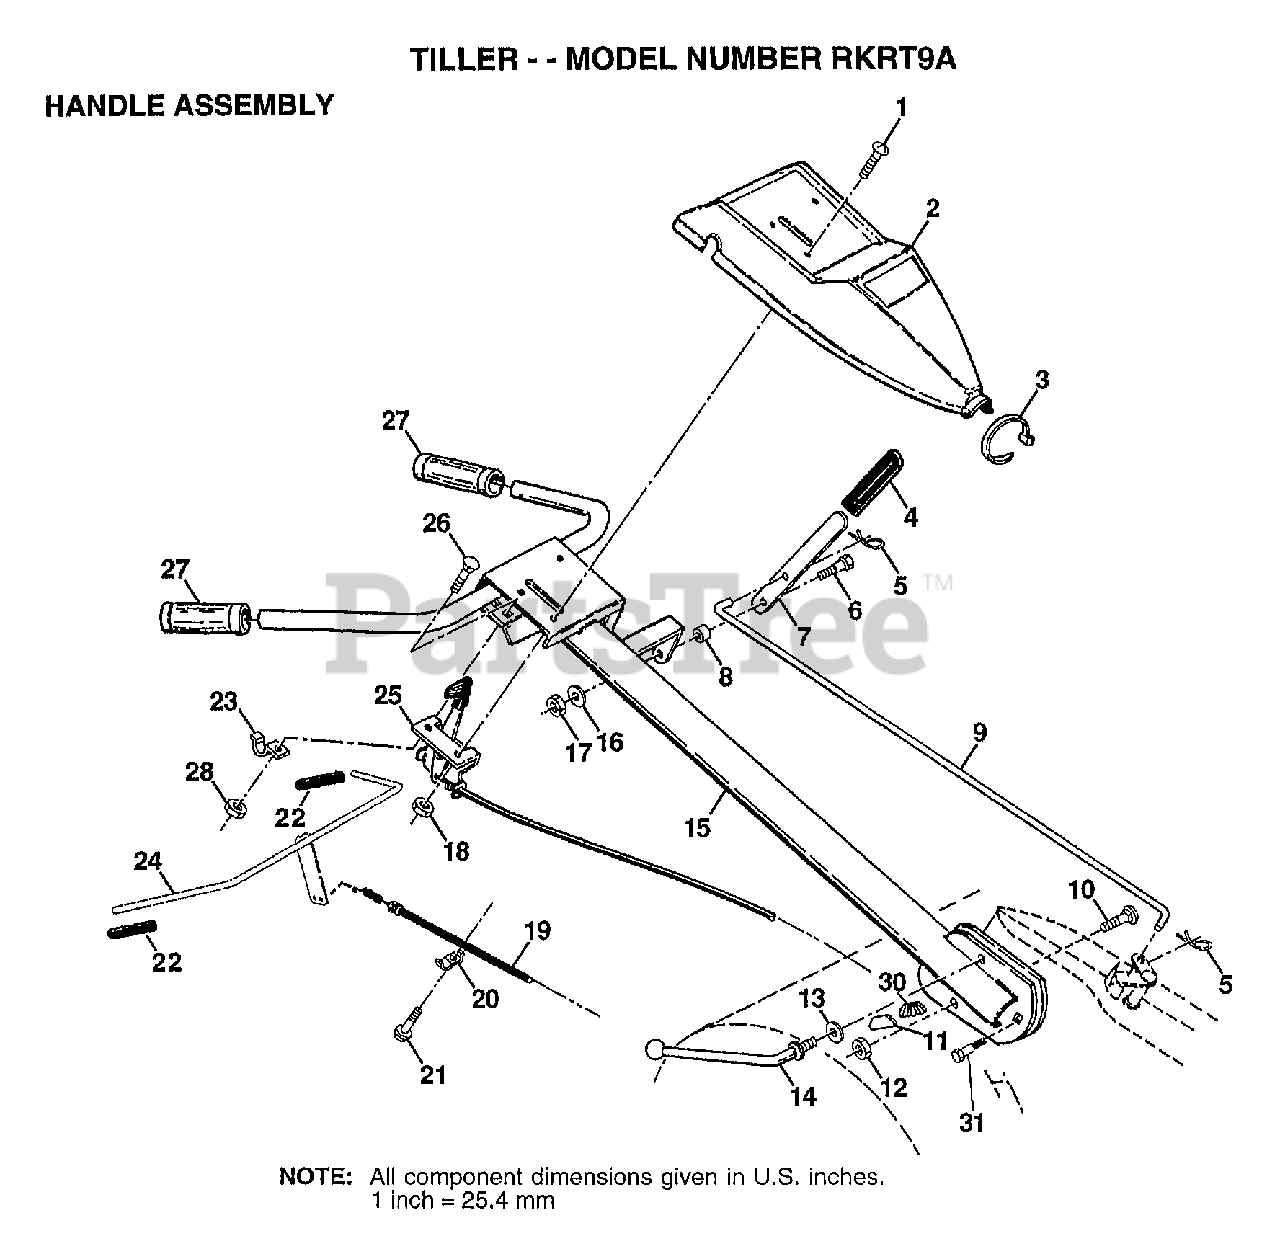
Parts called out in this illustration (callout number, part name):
1	SCREW.PNHD.10-24
2	PANEL.CONTROL
3	TIE CABLE CRT
5	RETAINER M
6	SHOULDER BOLT ST
7	SHIFT HANDLE CRT
8	GROMMET CRT
9	ROD.SHIFT
10	BOLT D
11	LOCK CRT
12	LOCKNUT
13	WASHER CRT
14	LEVER LOCK CRT
15	HANDLE.ASM.PNT
16	LOCKWASHER
19	CABLE.CLUTCH
20	CONDIUT CLIP T
22	GRIP BAR CRT
24	BAR ASM CONTROL
25	CONTROL.THROTTLE
26	BOLT
28	LOCK.HANDLE
29	BOLT PIVOT
30	NUT
